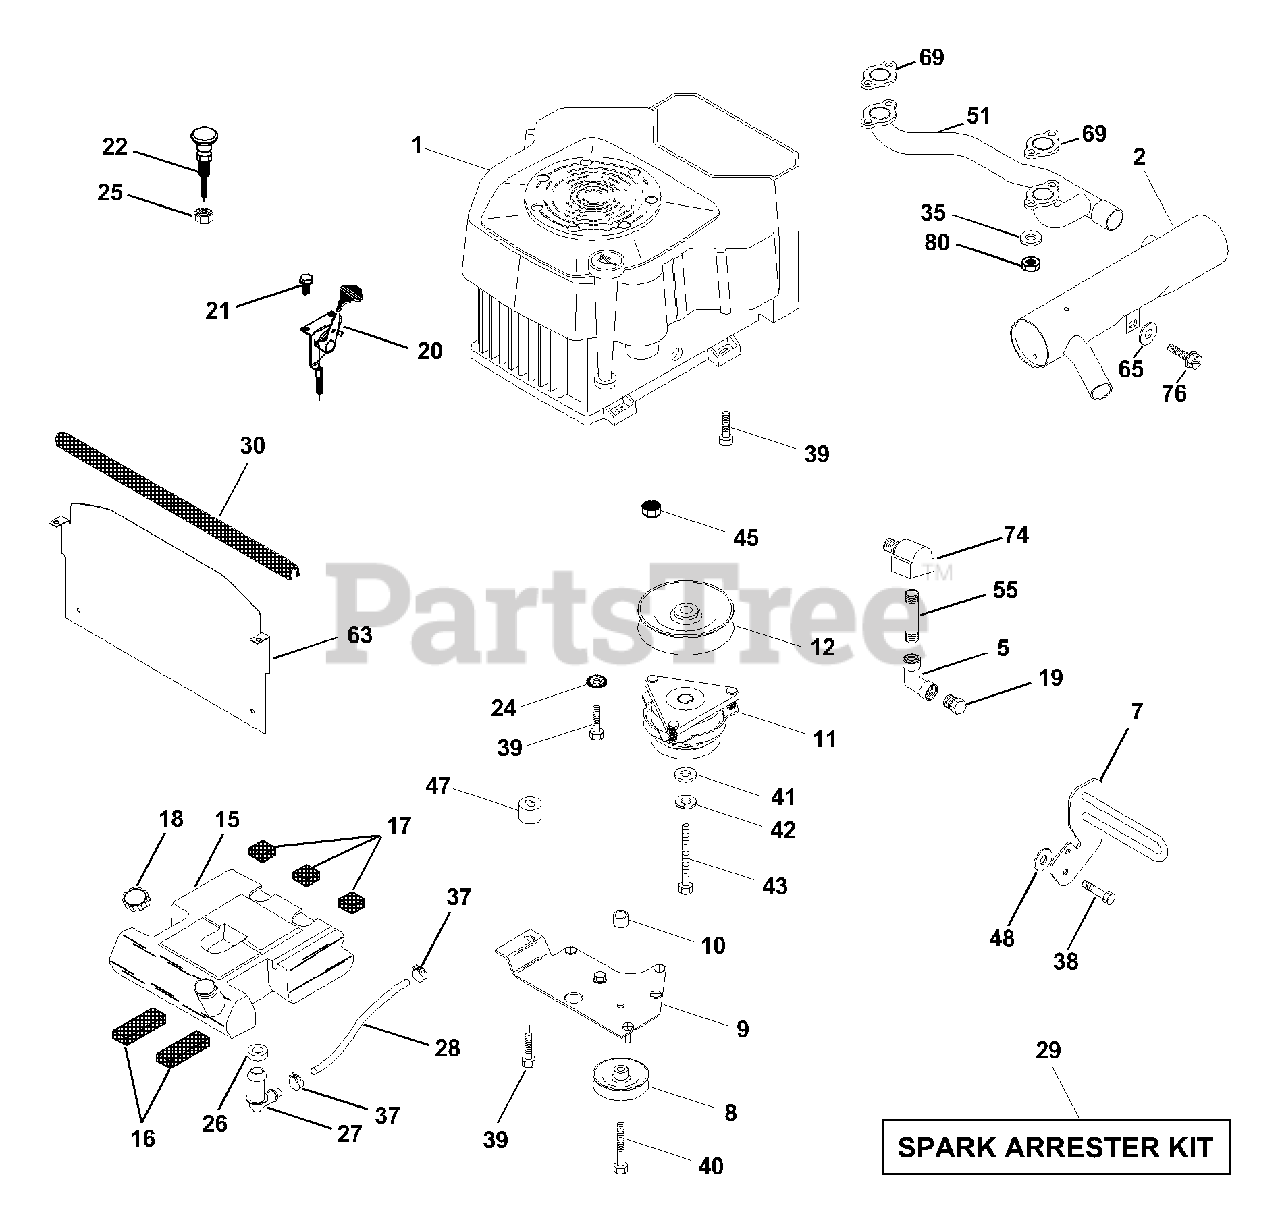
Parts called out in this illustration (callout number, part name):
2	Muffler Side 1-1/4
5	Elbow STD 90 Degree 3/8-18 NPT
7	Muffler Assembly Guard
8	Pulley V-Idler
9	Keeper Asm Belt Engine VGT 96
11	Clutch Electric
12	Pulley Engine VGT Elect Clutch
15	Tank Fuel Rear
16	Pad Spacer
17	Pad Spacer
18	Cap Asm Fuel W/Sym Vented
19	Plug Oil Drain
20	Control Throttle
21	Screw Hex Thd Cut 1/4-20 X 5/8
22	Control Choke
24	Washer Ext Tooth 3/8
25	Nut Keps 3/8 - 24 UNF
26	Bushing
27	Stem Tank Fuel
28	Fuel Line
29	Spark Arrester Kit
30	Extrusion Hood
35	Washer Split
37	Clamp Hose
38	Screw 3/8-16 x 1-1/4
39	Screw TT 3/8-16 x 2-1/4 UNC
40	Screw TT 3/8-16 x 4 UNC
41	Washer 1-1/2 OD X 15/32 ID X .250
42	Washer Lock 7/16
43	Bolt Hex 7/16-20 X 4-1/4 Ga 5
45	Nut Keps Hex 1/4-20 Unc
47	Spacer Engine
48	Washer 13/32 x 1-1/4 x 7 Ga.
51	Manifold Pipe VGT CV 1-1/4
55	Nipple, Pipe 4-1/2
63	Shield, Heat VGT YP/Husq.
65	Washer 13/32 x 1 x 14 Ga.
69	Gasket Kohler
74	Elbow Street Brass
76	Screw 3/8-16 x 3/4
80	Nut Flange M8-1.25
